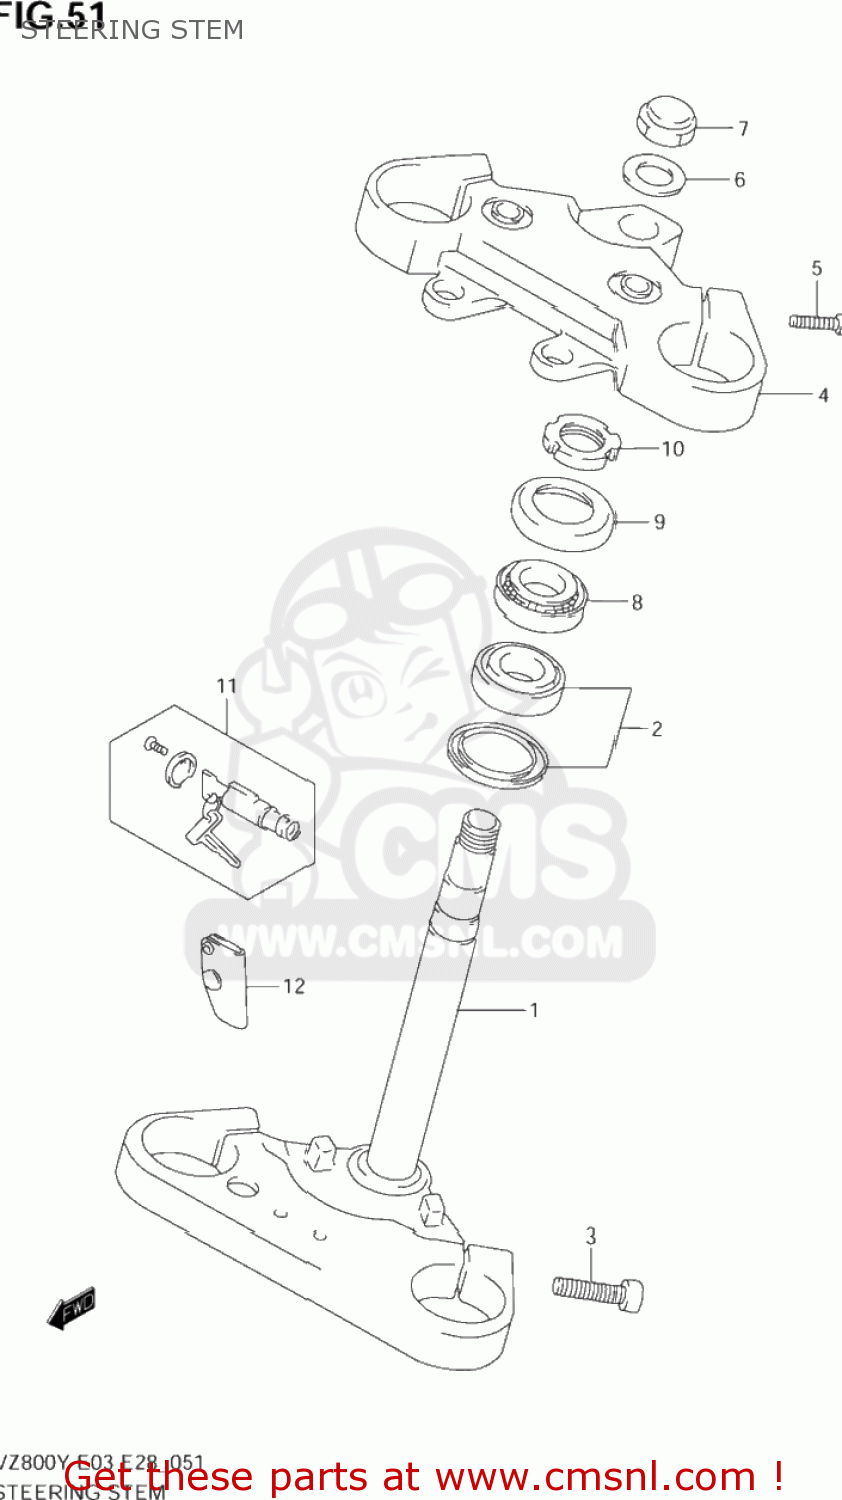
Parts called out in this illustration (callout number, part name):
1	STEM,STEERING
2	BEARING(30X55X17)
3	BOLT,STEM
4	HEAD,STEERING STEM
5	BOLT,STEM HEAD
6	WASHER(22.5X35.9X1.6)
7	NUT,CAP
8	BEARING(25X47X15)
9	SEAL,STEERING UPR DUST
10	NUT,STEERING STEM(25X44X10)
11	LOCK SET,STEERING
12	CASE,STEERING KEY
